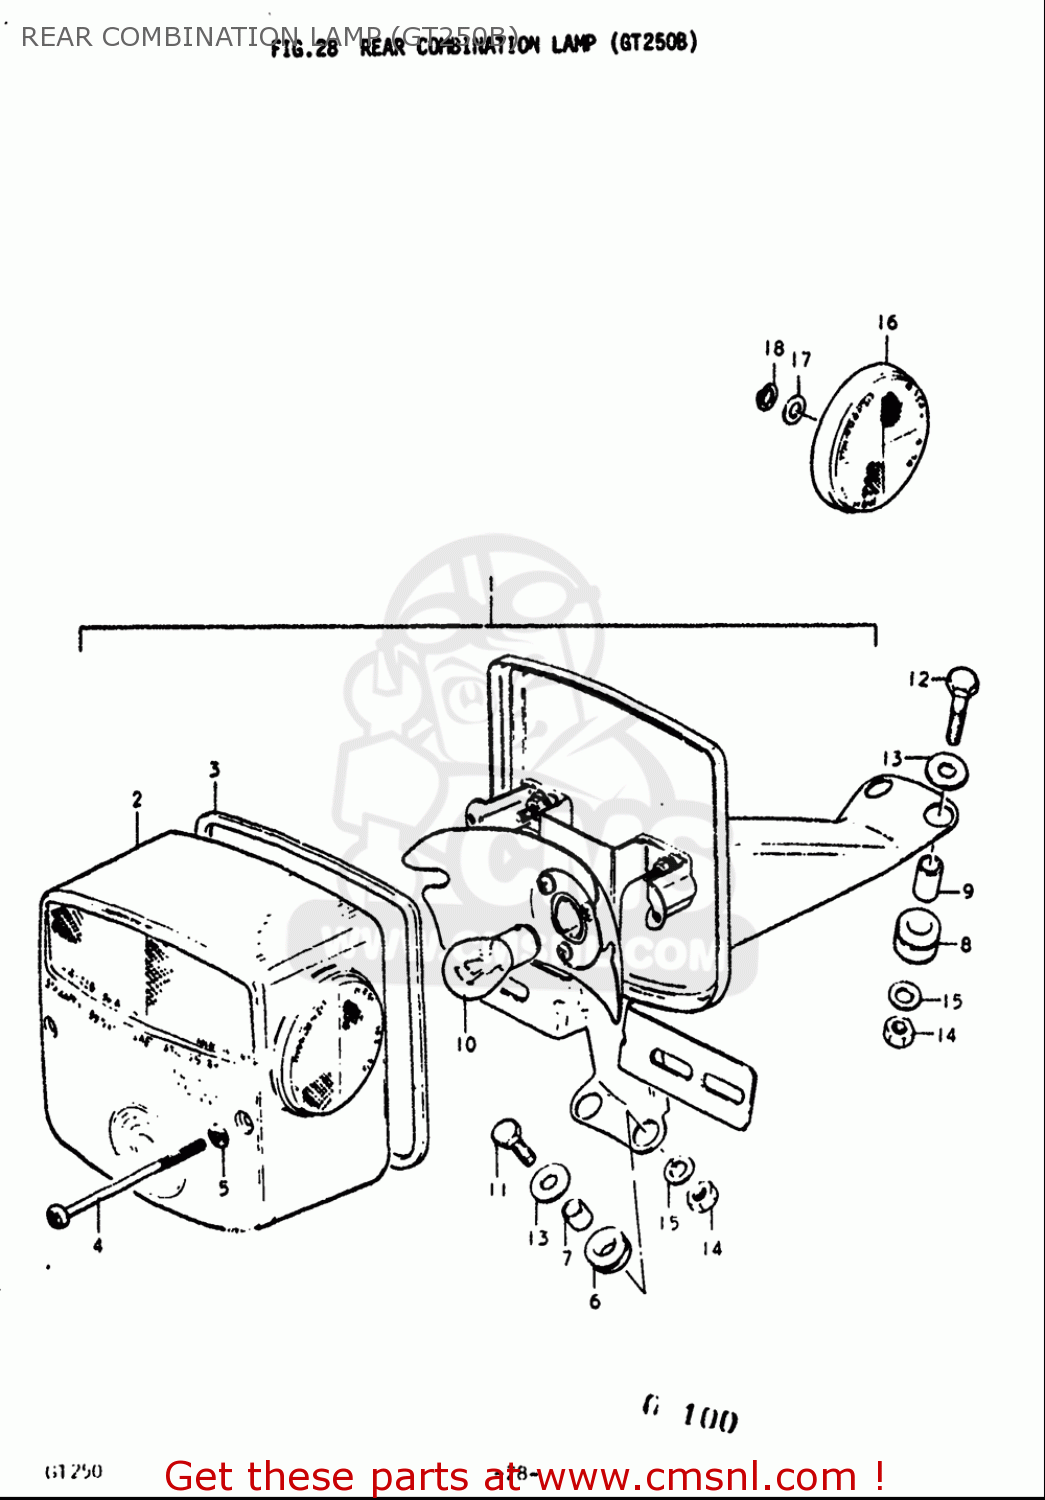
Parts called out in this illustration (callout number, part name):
2	LENS
3	GASKET (NAS)
5	GASKET (NAS)
6	CUSHION
7	SPACER
8	CUSHION
9	SPACER
10	BULB(12V23W)
11	BOLT
12	BOLT
13	WASHER(6.5X20X1.2)
14	NUT
15	WASHER
16	REFLEX REFLECTOR,FR
17	WASHER
18	WASHER,LOCK
